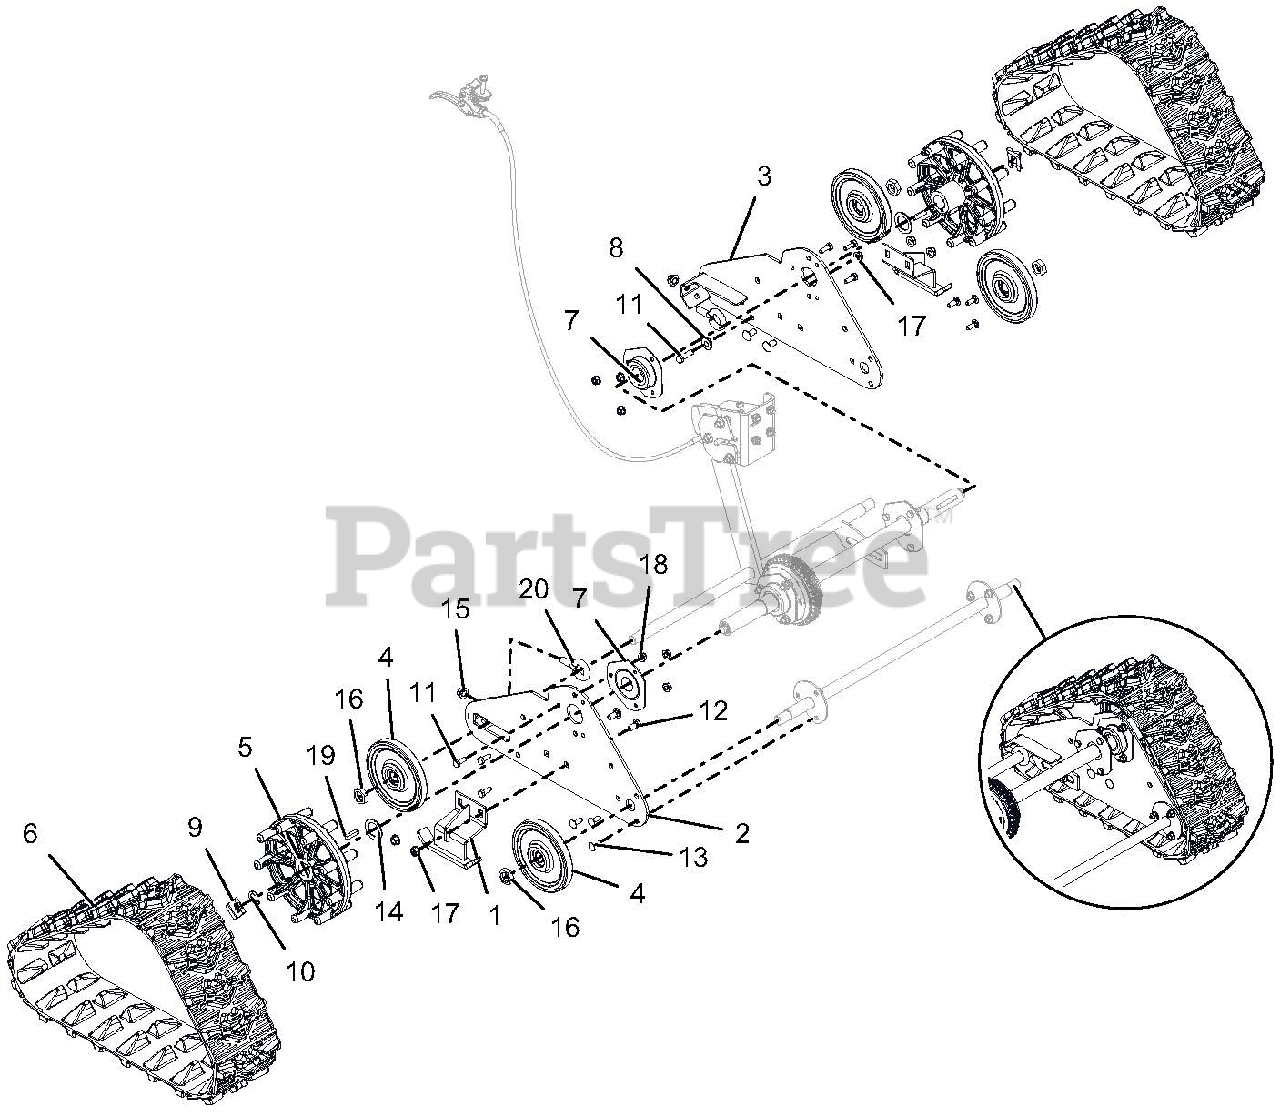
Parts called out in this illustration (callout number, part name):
1	RUNNER, GUIDE-TRACK
2	SIDE PLATE, RH-TRACK
3	SIDE PLATE, LH-TRACK
4	WHEEL, BOGIE - SINGLE BEARING
5	WHEEL, MACHINED DRIVE
6	TRACK, RUBBER
7	BRG-FLG 1.003/1.000 3 BOLT
8	BSHG-FLG .325X.499X.3X.875
9	CLIP, SNAP .625 DIA
10	RG-RTNG-EXT .625X.042
11	@BLT-HEX .25-20X.75 GR5 YWZC
12	@BLT-RDHDSQNK .31-18X.75 G5YZ
13	@BLT-RDHDSQNK .25-20X.75 G5YZ
14	WSHR-FL-STL 1.010X1.505X.062YZ
15	@NUT-LK-CTR-FLG .25-20 YWZC
16	@NUT-LK-NYL .625-18 YWZC
17	@NUT-LK-TOP-FLG .31-18 YWZC
18	@NUT-LK-TOP-FLG .25-20 YWZC
19	KEY-RECT .25X.188X1.00
20	BLT-EYE .375-16X.880 YWZC
